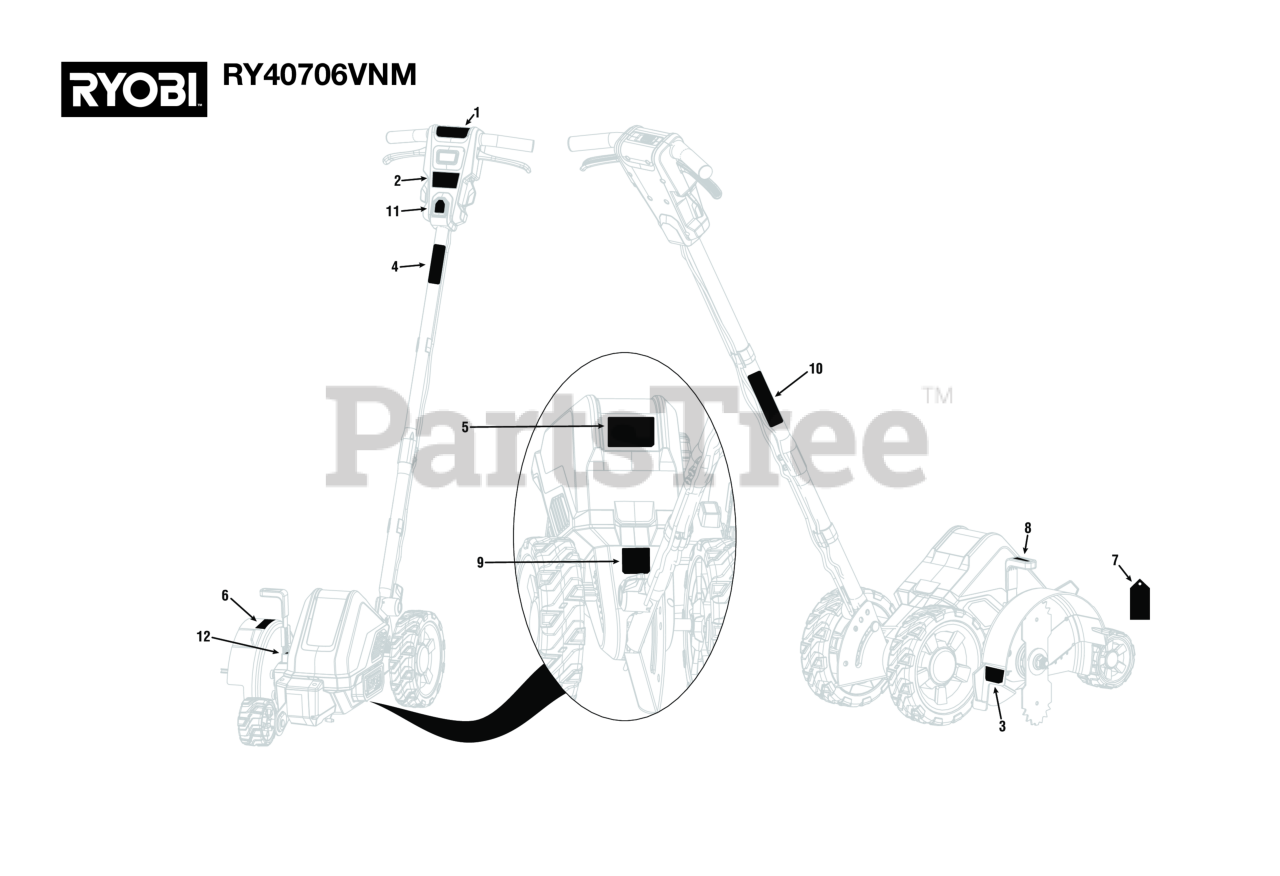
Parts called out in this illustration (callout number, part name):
1	Blade Speed Label
2	Starting Instructions Label
3	Guard Icon Label
4	Icon Label
5	Data Label
6	Blade Guide Label
7	Cleanout/ Edge Guard Hangtag
8	Edge Guide Label
10	Warning Label (Fr/Sp)
11	Press to Rotate Label
12	Blade Change Label
